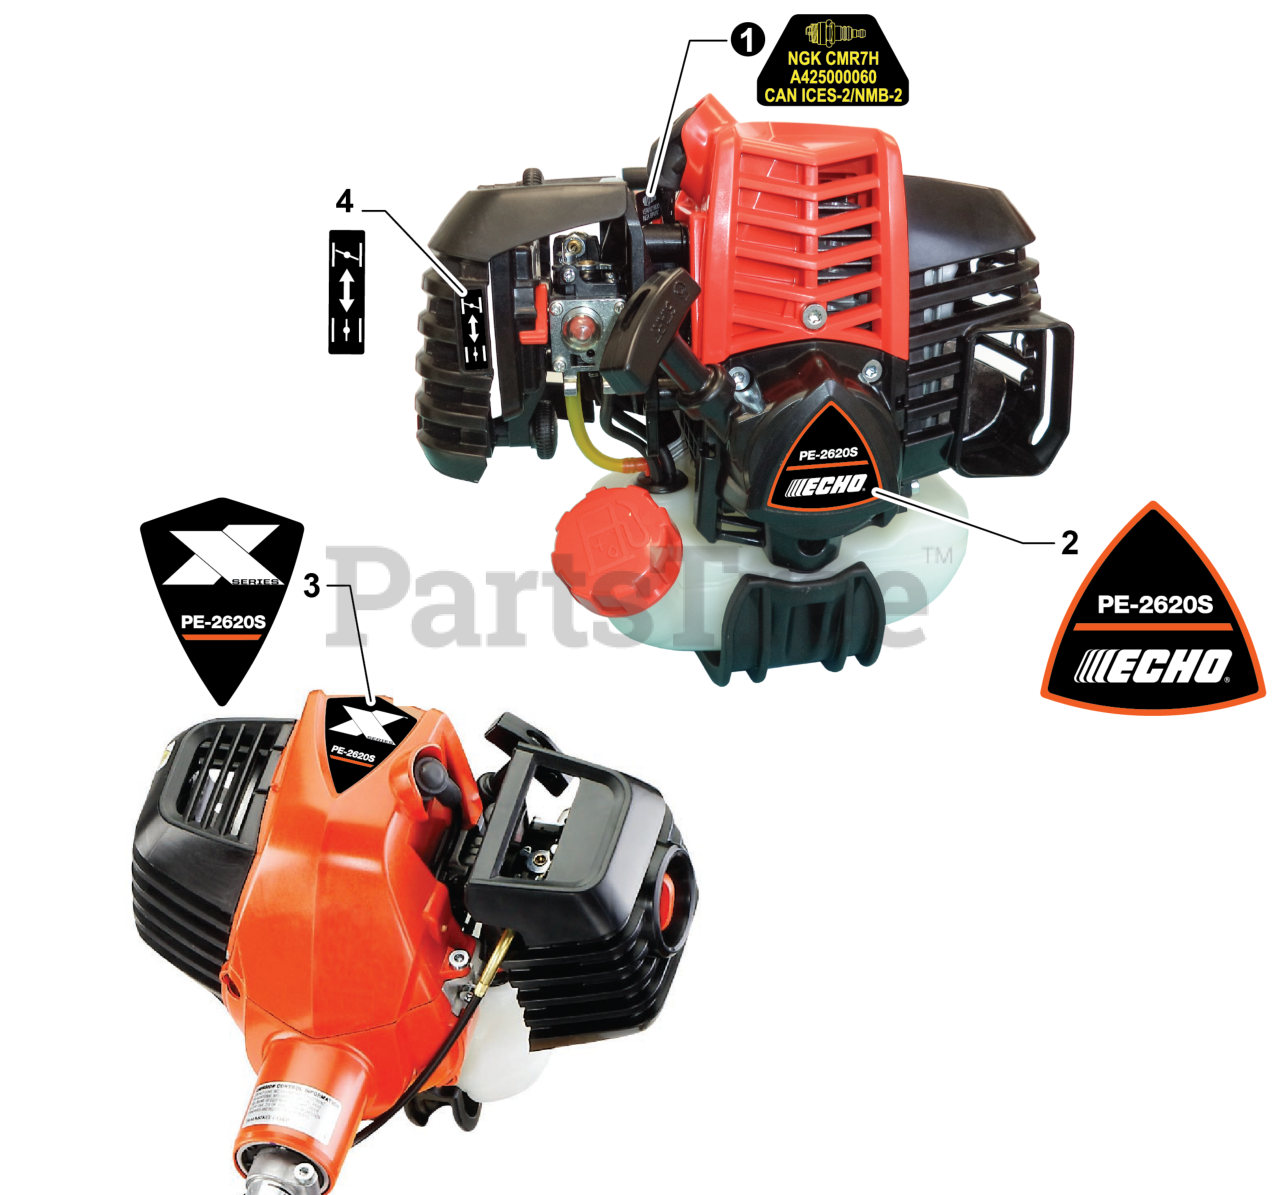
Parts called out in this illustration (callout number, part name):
1	LABEL - SPARK PLUG - CMR7H
2	LABEL - RECOIL STARTER - PE-2620S
3	LABEL - MODEL PE-2620S
4	LABEL - CHOKE
